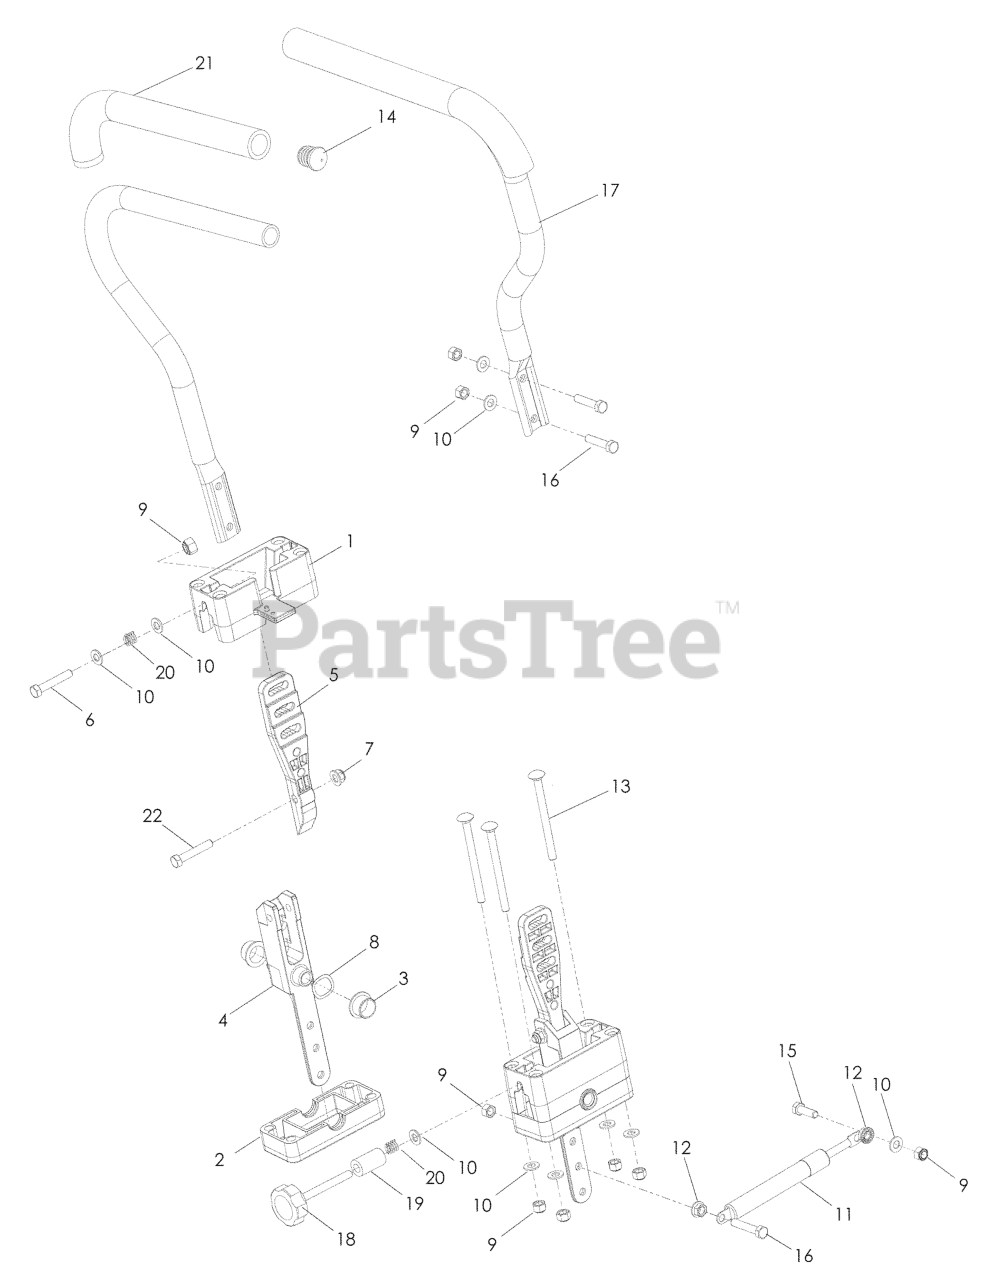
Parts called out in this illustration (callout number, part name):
1	BLOCK, UPPER
2	BLOCK, LOWER
3	BEARING, FLANGE
4	PIVOT SECTION, DRIVE
5	MOUNT, DRIVE CONTROL
6	HCS 5/16-18 x 2 TPBLT
7	NUT 5/16-18 FLANGE NYLOC
8	WASHER, .825 x 1.087 WAVE
9	NUT 5/16-18 HEX NYLOC
10	WASHER 5/16 SAE FLAT
12	NUT 5/16-18 HEX WHIZLK
13	RHSNB 5/16-18 x 4
15	HCS 5/16-18 x 1
16	HCS 5/16-18 x 1½
17	LEVER, w/GRIP
21	GRIP, FOAM
22	HCS 5/16-18 x 1¾
